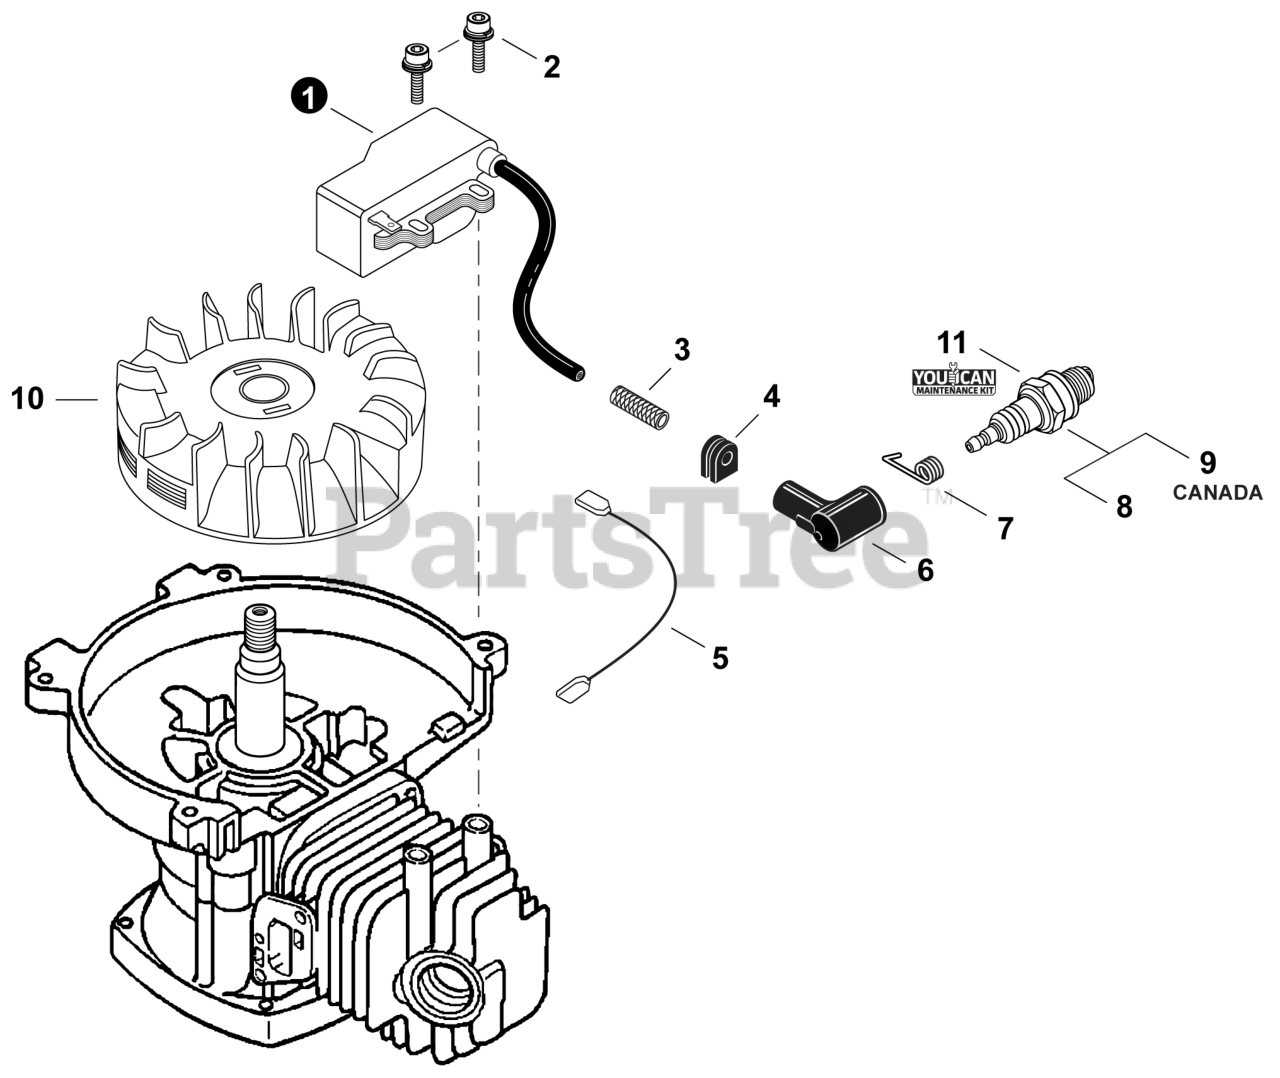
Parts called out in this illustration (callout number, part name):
1	COIL, IGNITION
2	BOLT 4x20
3	TUBE, INSULATOR
5	LEAD - IGNITION
6	CAP, SPARK PLUG
7	TERMINAL, SPARK PLUG
8	SPARK PLUG - BPM8Y
9	SPARK PLUG - BPMR8Y
10	FLYWHEEL
11	TUNE-UP KIT - YOUCANT
